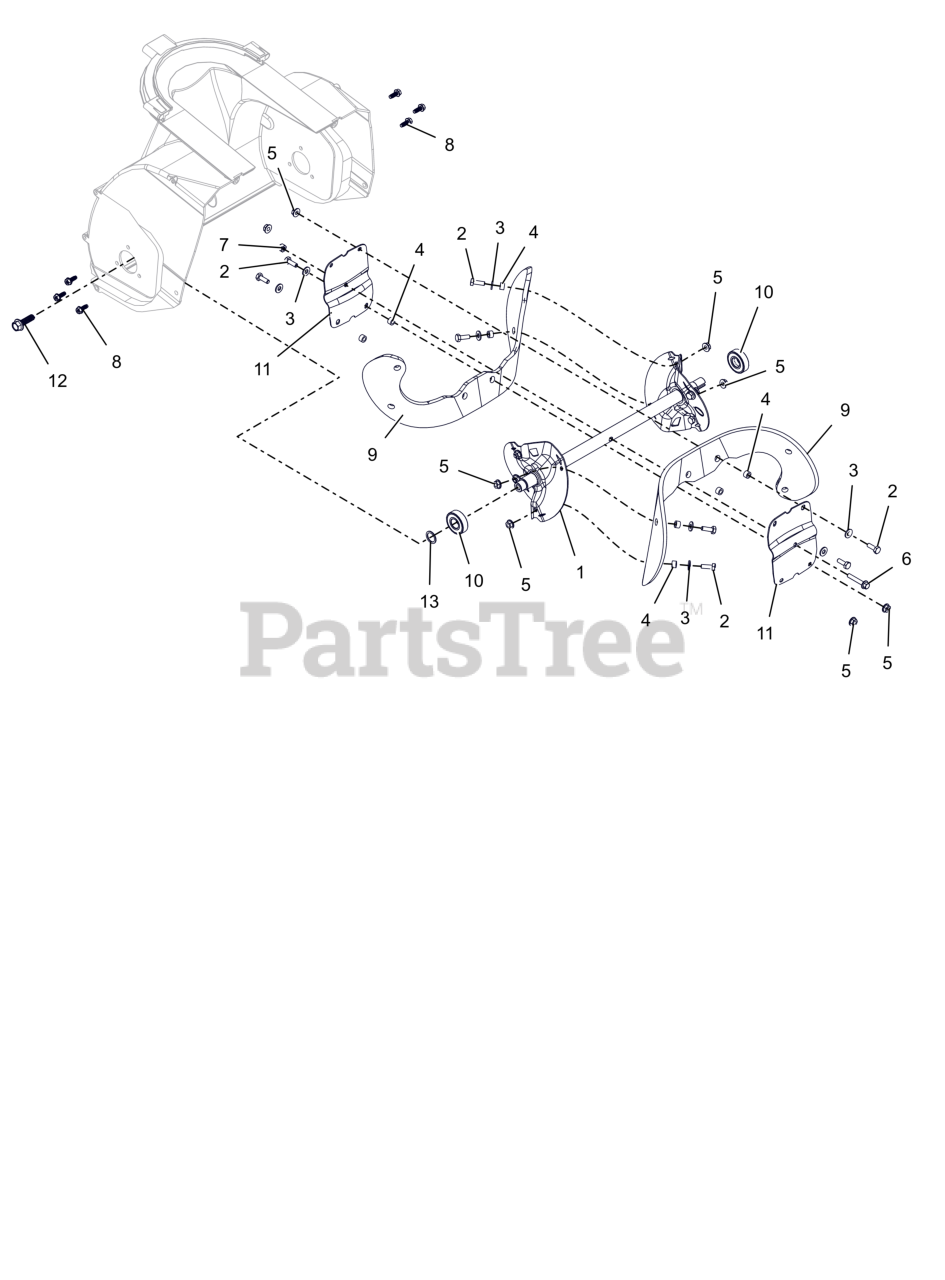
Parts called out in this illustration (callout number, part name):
1	WLDMT, ROTOR
2	BLT, HEX .25-20X.75 G5 ZCC
3	WSHR,FLT .281X.625X.065 ZCC
4	BUSHING, .26 ID X .44 OD X .26
5	NUT-LK-CTR-FLG .25-20 ZC120
6	BLT, HEX - FLG .25-20X1.5 BLACK
7	NUT, NYLON .250 - 20 (BLACK)
8	1/4-20 X 5/8 TAPTITE
9	KIT, PADDLE REPLACEMENT 18IN
10	BRG-BALL .669X1.575X.47(6203Y)
11	PLATE, CENTER AUGER
12	BLT, HEX -FLG .375-16X1.25 BLACK
13	WSHR, THRUST
